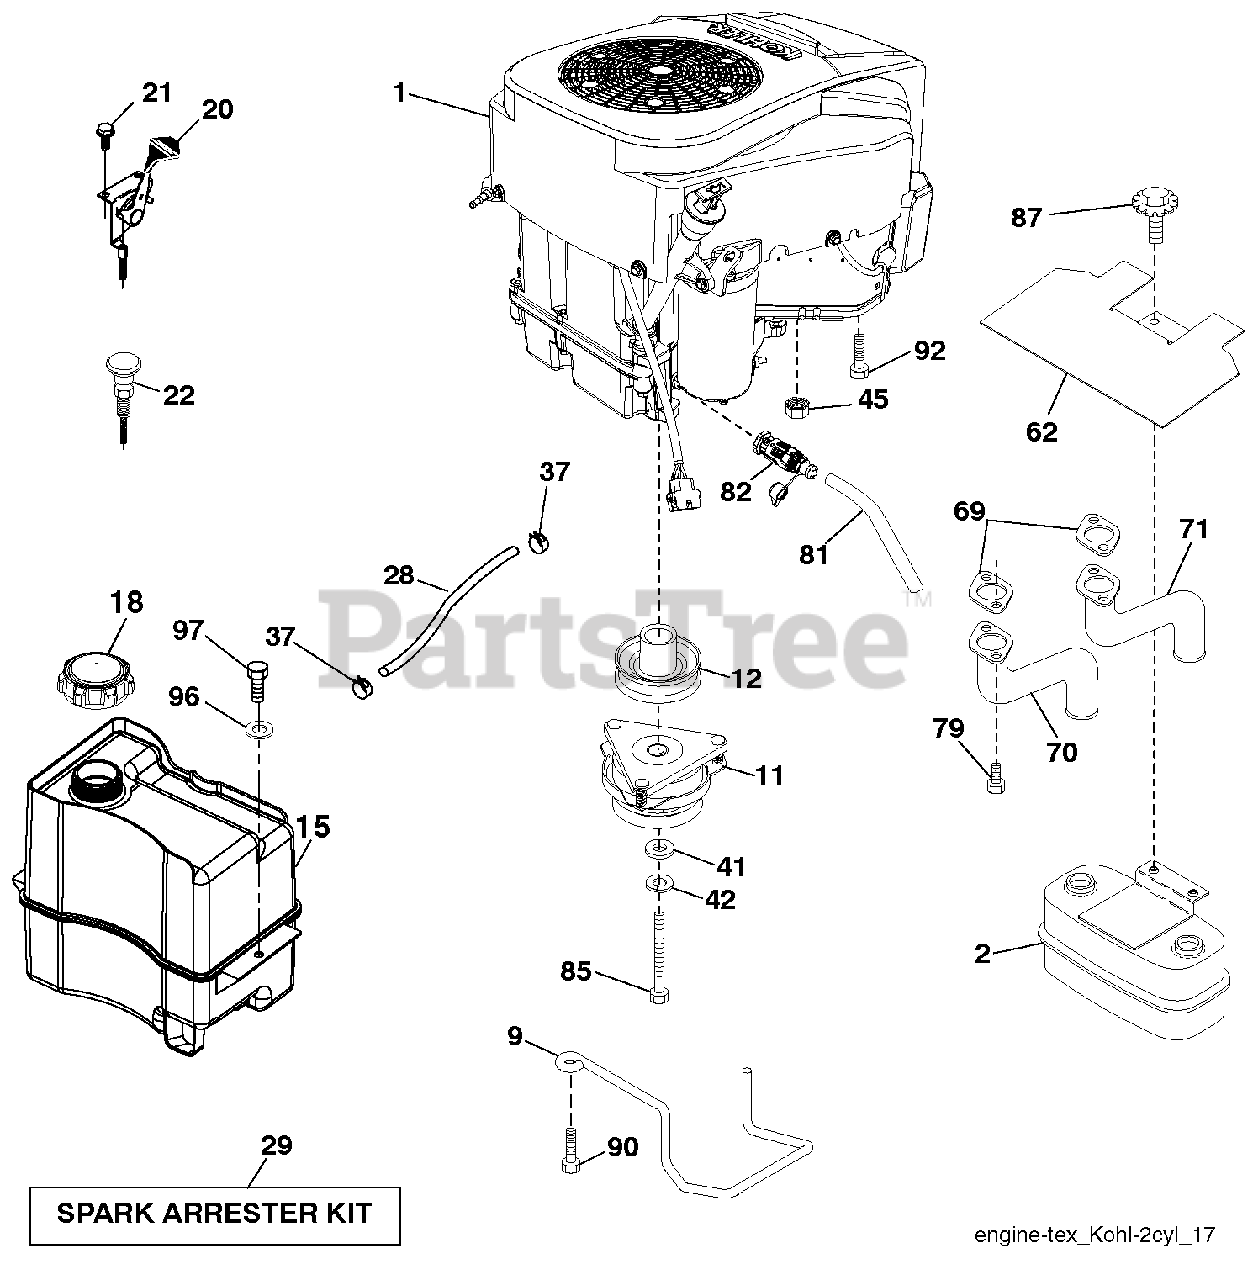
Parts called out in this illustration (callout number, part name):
2	MUFFLER.ASM.TWN.EXTNDED.DFLCTR
9	KEEPER BELT ENGINE
11	RB.CLUTCH.OGURA.4.4.PD
12	PULLEY.ENGINE.TUFFTORQ
15	TANK.ASSEMBL.2.5GAL.NON-EPA
18	CAP ASM.FUEL.2.25"FR.
20	THROTTLE CONTROL
21	SCREW.#10 X 0.750.BOS
22	CONTROL.CHOKE.ERGO.PUSH-IN.BLA
28	LINE.FUEL.64"REAR.EMIS
29	KIT.SPARK ARRESTOR 794945 B&S
37	HOSE CLAMP
42	LOCKWASHER
45	NUT
62	SHIELD.HEAT.MUFFLER
69	GASKET.EXHAUST.KOHL.CV18-CV26
70	PIPE.EXHAUST.LH.CV18/20
71	PIPE.EXHAUST.RH.CV18/20
79	SCREW.SOCKET HD.5/16-1
81	TUBE, DRAIN OIL ASM.
82	VALUE.OIL.DRAIN
85	BOLT HEX 7/16-20X4-1/4"
87	Bolt, 5/16-18 X 1-3/4
90	SCREW 3/8-16X1
92	SCREW 3/8-16X1
97	SCREW HEXWSHR 1/4-20X3/4
